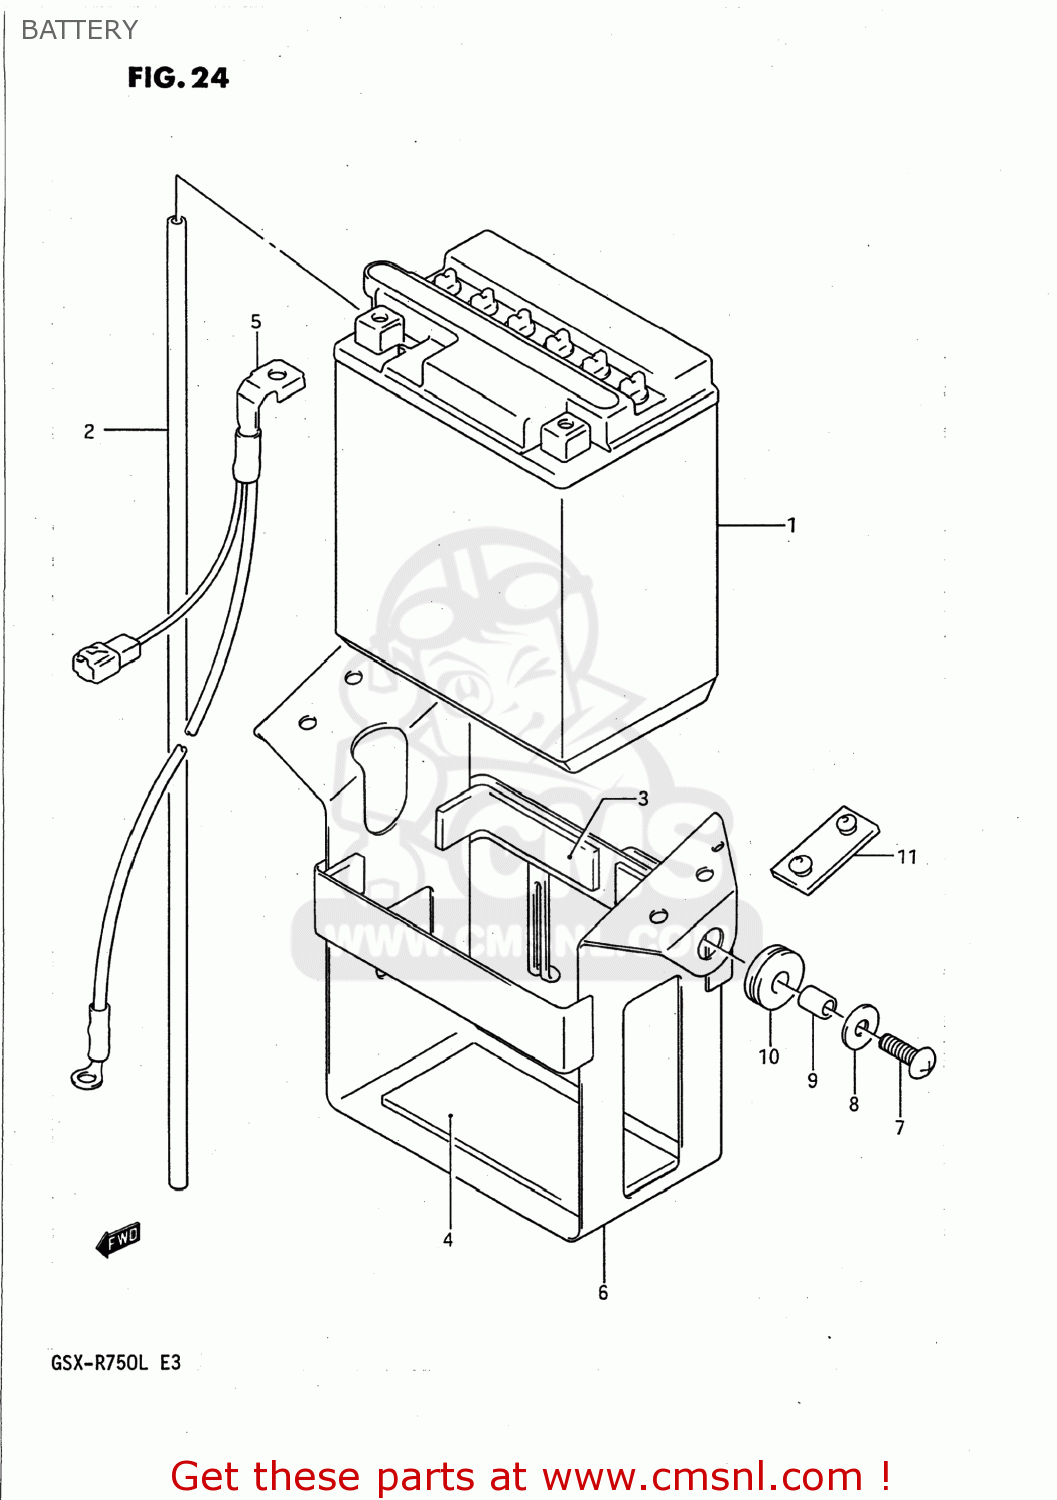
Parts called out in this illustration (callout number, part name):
1	BATTERY ASSEMBLY
2	HOSE,BATTERY EXHAUST
3	PROTECTOR,20X9
4	PROTECTOR(170X95X3.0)
5	WIRE,BATTERY MINUS LEAD
6	HOLDER,BATTERY
7	SCREW
8	WASHER
9	SPACER
10	CUSHION
11	CUSHION
